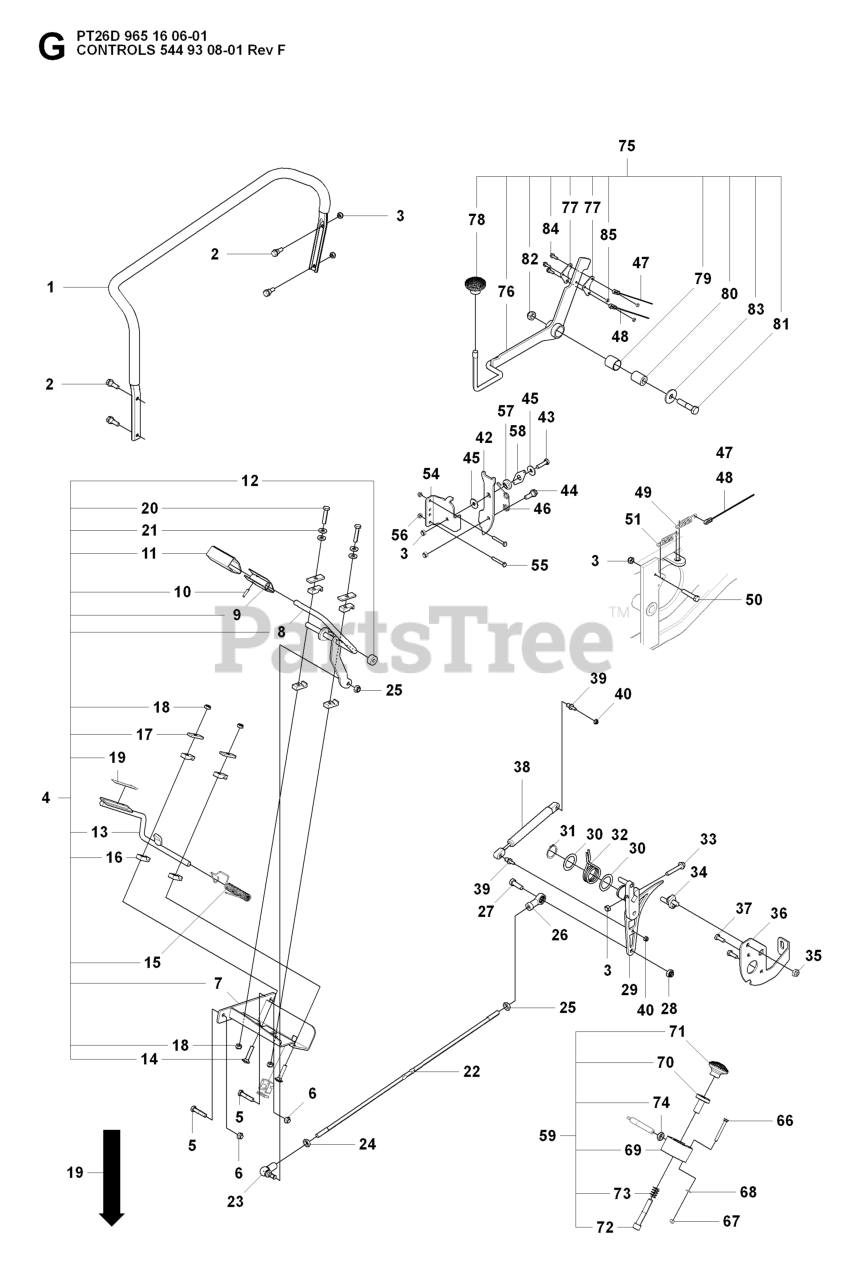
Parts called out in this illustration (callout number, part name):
1	HANDLE ASSY
3	LOCKNUT M8
6	LOCKNUT M8
11	PEDAL RUBBER
14	Screw Mvbf 8 X 40
18	NUT
21	WASHER - 15X7.3X1.6
25	NUT
28	NUT
30	WASHER SPACER 32X45X1,0
33	SCREW
40	LOCKNUT M6
43	SCREW
50	SCREW
56	LOCKNUT M6
66	SCREW M6X55
67	LOCKNUT M6
68	WASHER
71	KNOB
78	KNOB
79	BUSHING
84	SCREW M6S 5X20
85	LOCKNUT M5
